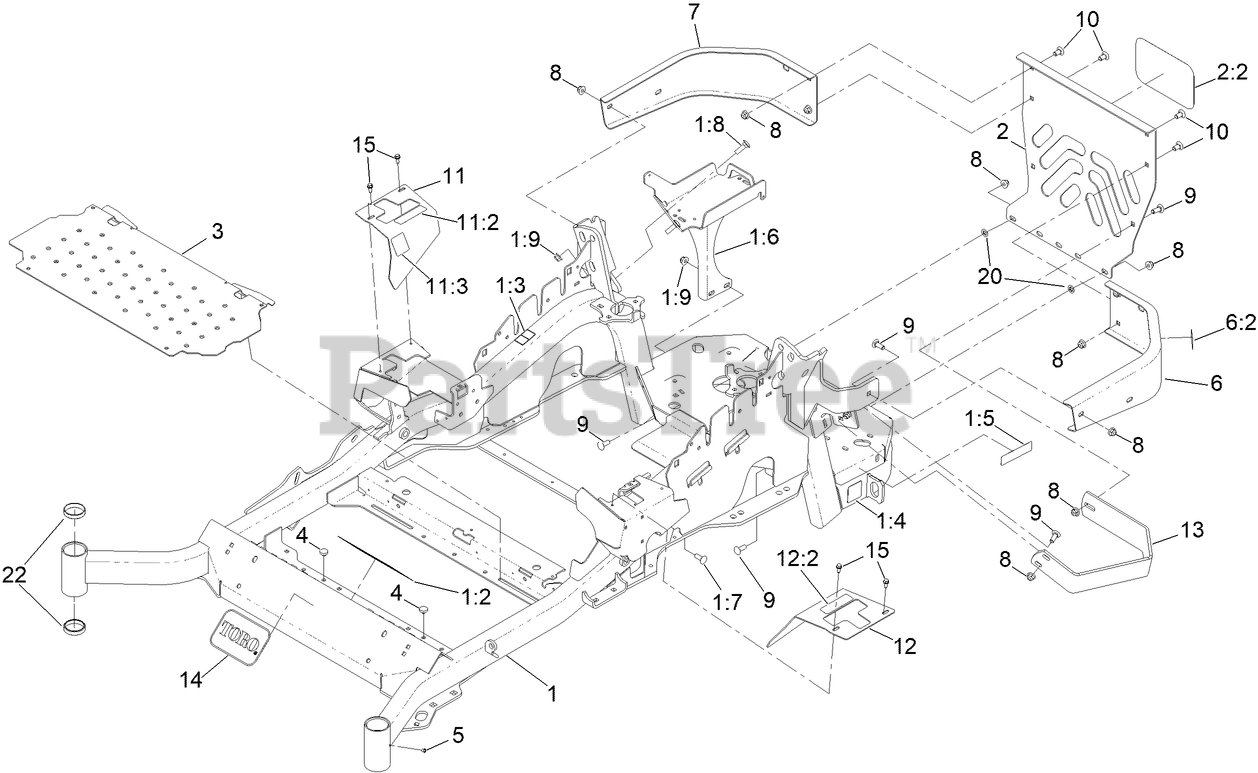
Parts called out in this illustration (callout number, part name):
1	MAINFRAME SERVICE ASM - 60
1:2	DECAL-DANGER
1:3	DECAL-WARNING
1:4	DECAL-HAZARD, PINCHED FINGER
1:5	DECAL-ARRESTOR, SPARK
1:6	BATTERY MOUNT ASM
1:7	SCREW-CARR
1:8	BOLT-CARR
1:9	NUT-HF, NI
2	REAR GUARD ASM
2:2	DECAL
3	FLOORPAN
4	BUMPER
6	LH BUMPER ASM
6:2	DECAL-WARNING
7	BUMPER-RH
8	NUT-HF, NI
9	SCREW-CARR
10	SCREW-CARR
11	RH MOTION CONTROL COVER ASM
11:2	DECAL-CONTROL, MOTION
11:3	DECAL-PARK BRAKE, CE
12	LH MOTION CONTROL COVER ASM
12:2	DECAL-CONTROL, MOTION
13	GUARD-MUFFLER
14	DECAL
15	SCREW-HWH
20	NUT-PUSH
22	CUP-BEARING
